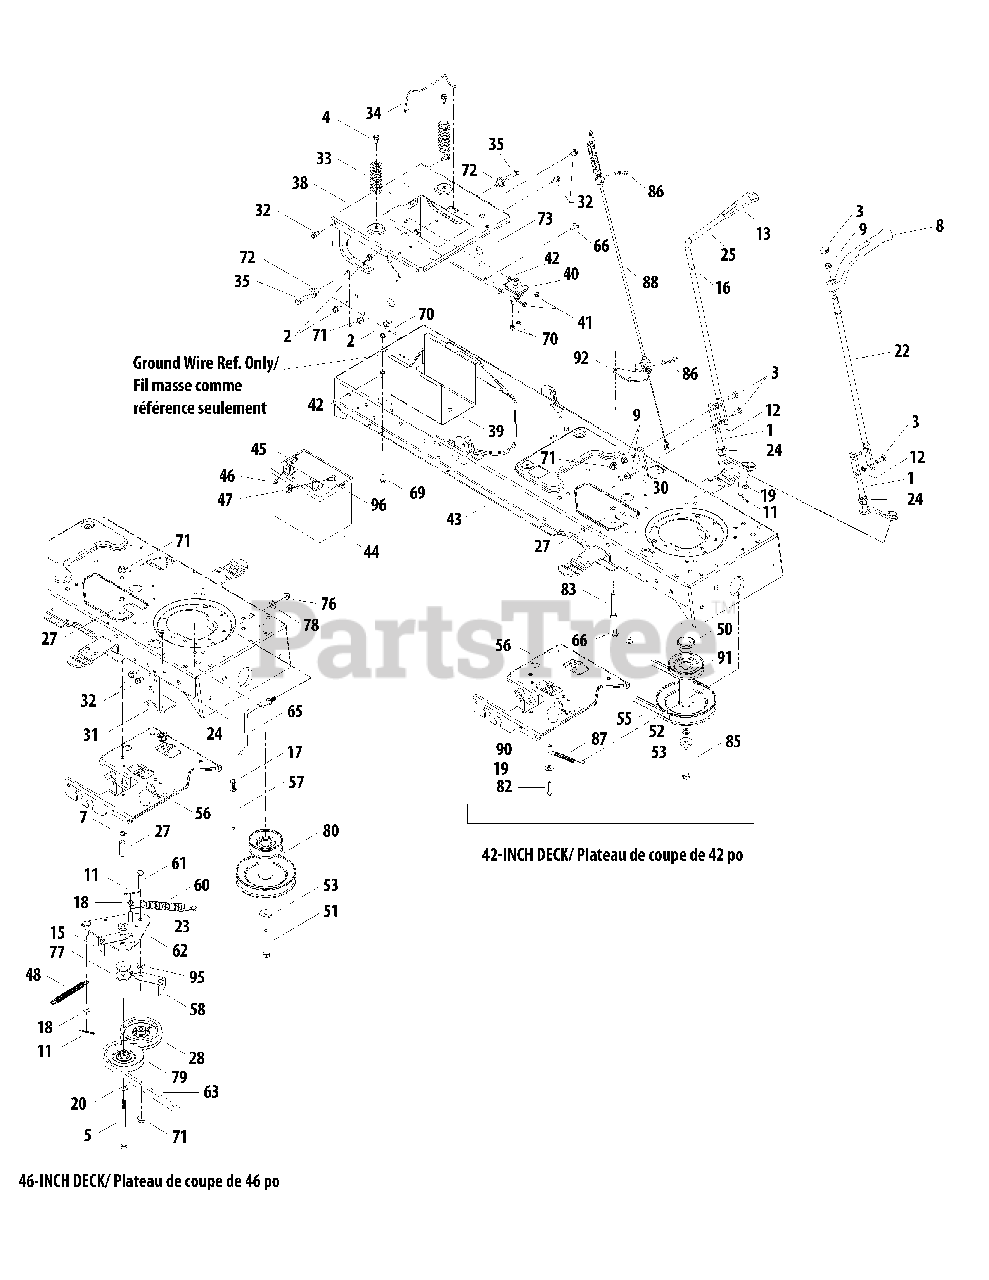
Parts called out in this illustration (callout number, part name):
1	PTO Engage Lever Assembly
2	Hex TT Scr. 5/16-18 x .75
3	Carriage Bolt 5/16-18 x 1.00" Lg
4	Hex Wash HD AB Tap Scr 5/16-12 x .75
5	Hex Cap Screw, 3/8-16 x 1.5
7	Push Nut Bolt Retainer
9	Hex Flange L-Nut 5/16-18
11	Cotter Pin 1/8" Dia x 1.00
12	Push Speed Nut
16	Flat Washer .510 ID x .75 OD x .033
17	L-Wash 5/16 ID
18	Flat Washer .385 ID x .62 OD x .06
19	Flat Washer .28 ID x .74 OD x .063
20	Flat Washer .385 ID x .87 OD x .06
21	Cap Plug .812 dia.
22	Deck Engagement Handle
23	Shoulder Spacer
24	Hex Slpit Flange Bearing .50 ID
25	Deck Engagement Handle
27	Spacer .385 ID x .635 OD x 1.54
28	Flat Idler Pulley 3.5 OD
30	Engagement Stop Bracket
31	Deck Stop
32	Hex Wash HD AB Tap Scr 5/16 x .75
33	Compression Spring 1.28 x 3.125
34	Battery Retainer Rod
35	Hex Bolt 3/8-16 x 1.25
38	Frame Seat Bracket
41	Hex Wash S-Tapp Scr 1/4-20 x .50
42	Ext. L-Washer 1/4 ID
43	Lower Frame Assembly
44	Battery 245 CCA (Dry)
45	Carriage Bolt 1/4-10 x .75
46	Sems Hex Nut 1/4-20
47	Wing Nut 1/4-20 Thd.
48	Extension Spring .50 x 5.0
50	Spacer 1.010 x 1.4 x .825
51	Hex Bolt 7/16-20 x 2.75 Gr. 5
52	Flat Washer .450 x 1.25 x .164
53	Lockwasher 7/16 ID
55	PTO Belt (w/42" deck)
56	Steering Support Bracket
57	Keeper Pin 5/16 x 4.75
58	Belt Guard
60	Extension Spring .75 x 6.75
61	Hex TT Sems Scr. 3/8-16 x 1.5
63	PTO Belt (w/46" Deck)
65	Belt Keeper Rod
66	Hex Wash HD S-Tapp Scr 5/16-18 x .50
68	L-Wash 1/4 ID
69	Thd Form ing Scr. 1/4-20 x .75 Lg.
70	Hex L-Flanged Nut 1/4-20 Gr. F Nylon
71	Flange Lock-Nut 3/8-16 Gr. F Nylon
72	Shoulder Spacer .38 x 1.0 x .70
77	Flat Washer .39 ID x 1.5 OD x .135
78	Cupped Washer .345 ID x .88 OD x .060
79	4" Dia. V-Idler
80	Engine Pulley 3.39 x 6.12 Dia 46" Trans.
80	Engine Pulley 3.56 x 6.12 Dia 46" Hydro
82	Hex Bolt 1/4-20 x 1.5
83	Hex Cap Screw, 3/8-16 x 2.5
85	Hex Bolt 7/16-20 x 3.25 Gr. 5
86	Bow Tie Cotter Pin
87	Extension Spring .38 OD x 3.9 Lg.
88	Deck Engage Cable
90	Spacer .260 x .375 x 1.030 Lg.
91	Engine Pulley 3.39 x 6.12 dia 42" Trans
95	Flat Washer .406 ID x .812 OD x .134
96	Shoulder Screw, 1/4-20
